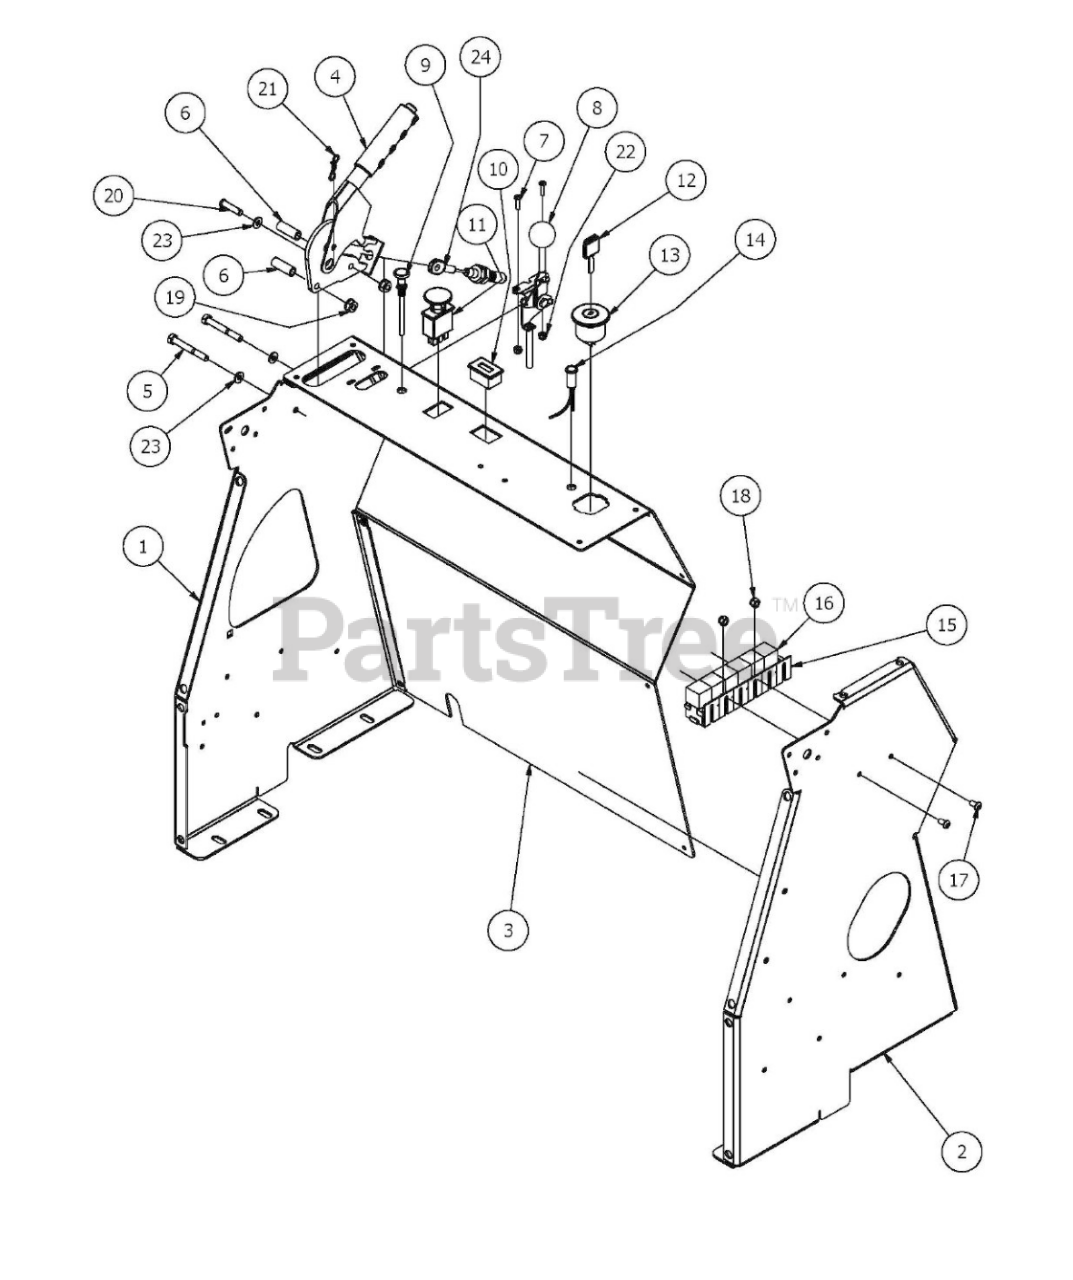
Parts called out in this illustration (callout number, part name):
1	2015 Podium Panel Left
2	2015 Podium Panel Right
3	2015 Podium Front Panel
4	Brake Handle- Stand On
5	5/16" x 2 1/2" Bolt
6	2017 Brake/Latch Spacer-Stand On
7	10-24 x 1 BS C/S 18-8 SS
8	Throttle-All Outlaws
10	Tachometer
11	PTO Engager
12	Ignition Key
13	Ignition Switch
15	Wiring Harness - 2015 Stand On
16	Relay Terminal
17	1/4" x 1/2" BS C/S 18-8 SS
18	1/4" Nylock Nut
19	5/16-18 Nylon Flange Nut
20	PIN .312 PIN
22	#10 Nylock Nut
23	1/4" Flat Washer
24	Brake Cable
